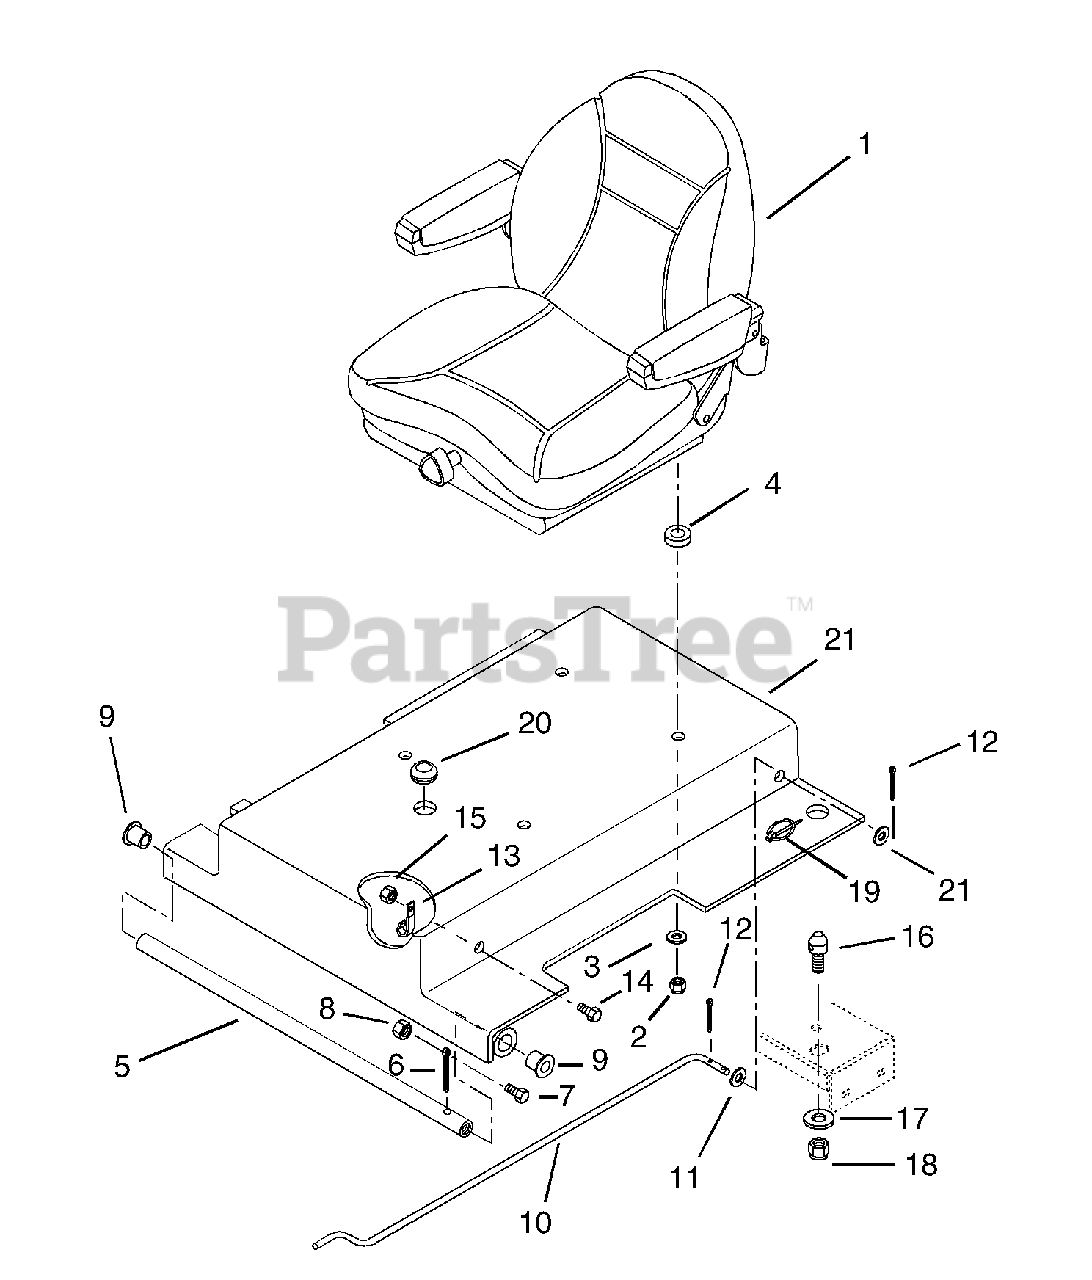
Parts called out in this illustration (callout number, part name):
1	Seat, Suspension
2	Nut-Locking-Center M8-1.25
3	Washer-Flat-Steel .38 x .875 x .083
4	Bushing-Sleeve .377 x .624 x .235
5	Shaft, Control
6	Pin, Cotter .25 x 2.00
7	Bolt-Hex .25-20 x 1.00 Grade 5
8	Nut-Locking-Center .25-20
9	Bushing, Flange .515 x .750 x .745 x 1.00
10	Rod, Stay
11	Washer-Flat-Steel .406 x .812 x .065
12	Pin-Cotter .09 x .75
14	Bolt-Hex .38-16 x .75 Grade 5
15	Nut-Locking-Center .38-16
16	Pin, Catch
17	Washer-Flat-Steel .531 x 1.06 x .095
18	Nut-Locking-Nylon .50-13
19	Pin-Klik .25 x 1.75
20	Grommet .75 x 1.06 x 1.38
21	Weldment, Seat Support
